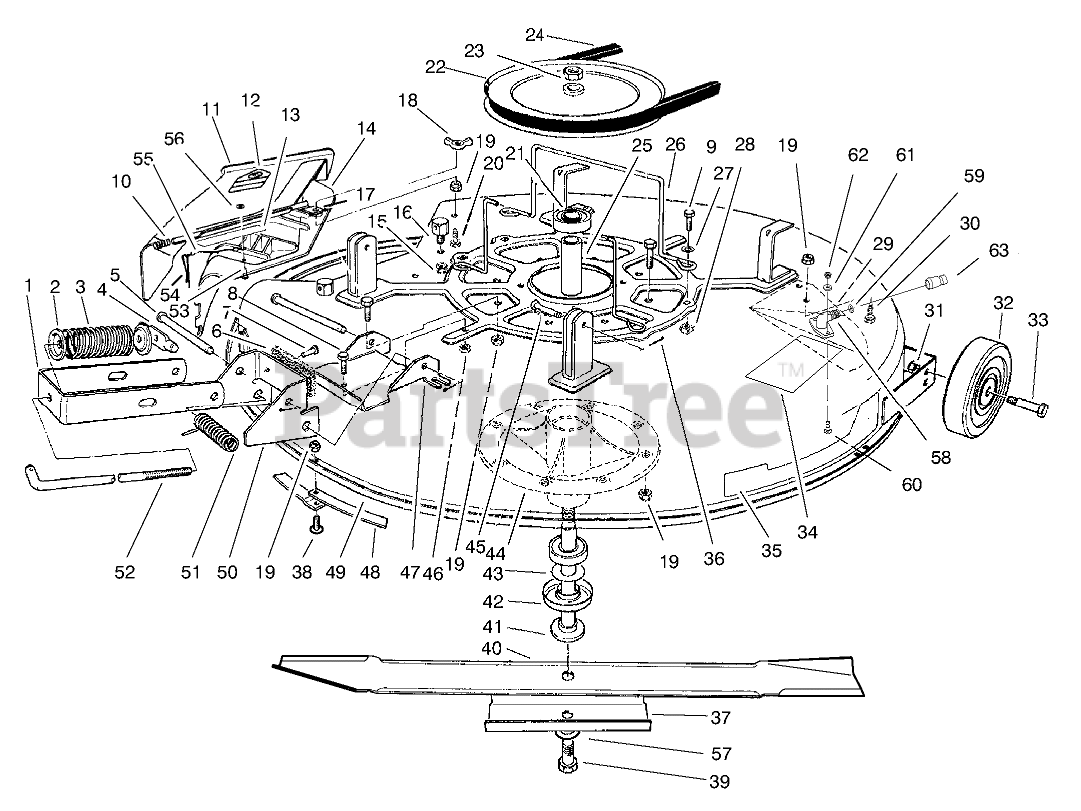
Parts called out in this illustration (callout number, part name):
1	Bracket-Engagement
2	RETAINER-SPR. TOP
3	SPRING-COMPRESSION
4	SHAFT-DECK ADJ.
5	PIN-CLEVIS
6	PAD-BRAKE
7	RIVET-BLIND
8	SCREW-HH
9	SCREW-HH
10	SPRING
11	Assembly-Deflector (Incl. Ref. #12)
12	DECAL-DANGER
13	DECAL-DANGER, DEFLECTOR
14	Assy.-Cover, Discharge (Incl. Ref. #53-56)
15	NUT-LOCK, NI
16	POST-PIVOT
17	Brace-Cover, Rear
18	NUT-WING
19	NUT-LOCK, NI
20	SCREW-HH
21	BEARING-BALL
22	PULLEY
23	NUT-HEX
24	V-BELT, DECK
25	SPACER-BEARING
26	GUIDE-BELT
27	WASHER-PLAIN
28	NUT-RETAINER
29	Kicker
30	SCREW-HH
31	NUT-LOCK, NI
32	WHEEL-DECK
33	BOLT-WHEEL
34	DECAL-DANGER, THROWN OBJECT
35	DECAL - RECYCLER 32"
36	PIN-COTTER
37	STIFFENER
38	SCREW-PPH
39	SCREW-HH
40	BLADE-RECYCLER
41	SHAFT-SPINDLE
42	SHIELD-BEARING
43	SPACER-HARDNED
44	SPINDLE
45	PIN-CLEVIS
46	NUT-HEX
47	Plate-Deck, Brake Mtg.
48	RING-DECK
49	Deck-Recycler (Incl. Ref. #13 & 34)
50	Brake Ass-y (Incl. Ref. #6-7)
51	SPRING
52	ROD-ENGAGEMENT
53	RIVET-BLIND
54	PIN-LOCKING, CHUTE
55	LANYARD
56	WASHER-PLAIN
57	WASHER-BELLEVILLE
58	FITTING-WASHOUT
59	O-RING
60	BOLT-CARR
61	WASHER-FLAT
62	NUT-LOCK, NI
63	CONNECTOR-HOSE
